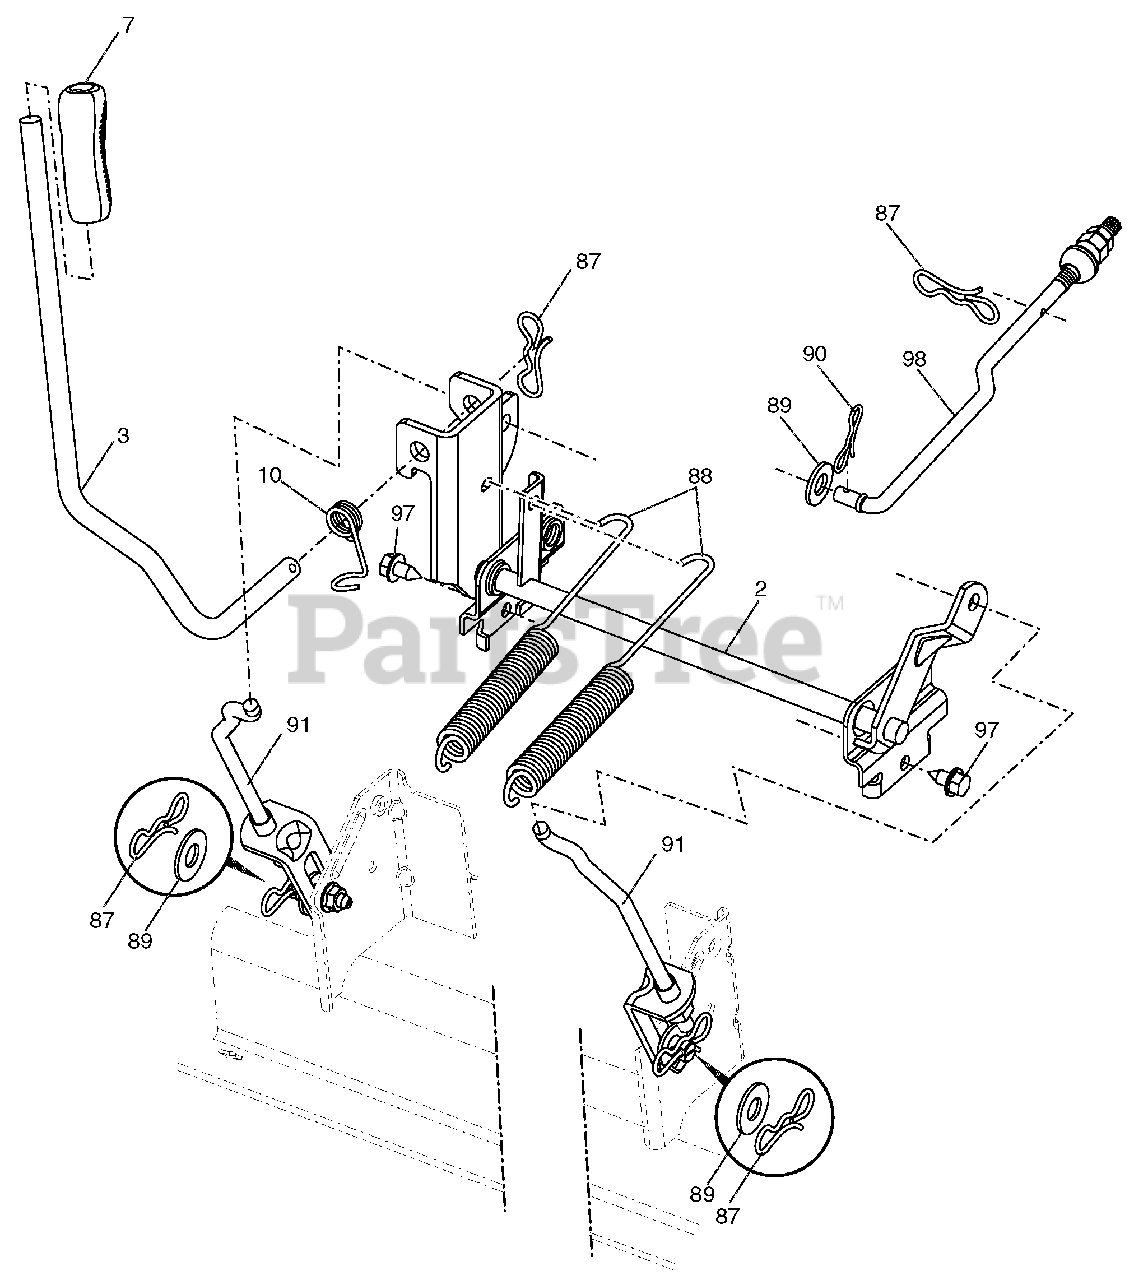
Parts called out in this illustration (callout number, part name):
2	SHAFT ASM., LIFT
3	LEVER ASM., LIFT RH
7	GRIP LEVER 5625 LD BLACK 428
10	SPRING.TORSION.HANDLE.LIFT
87	PIN.COTTER.7/16.BOW TIE LOCK
88	SPRING LIFT ASSIST
89	WASHER.CLEAR ZINC
90	PIN.COTTER.5/16.BOW TIE LOCK
91	LINK ASM.LIFT.54"TG
97	SCREW.HEXWSH THDR3/8-16X3/4.BL
98	LINK ASM.SUSP.FRONT.MWR.10.5
